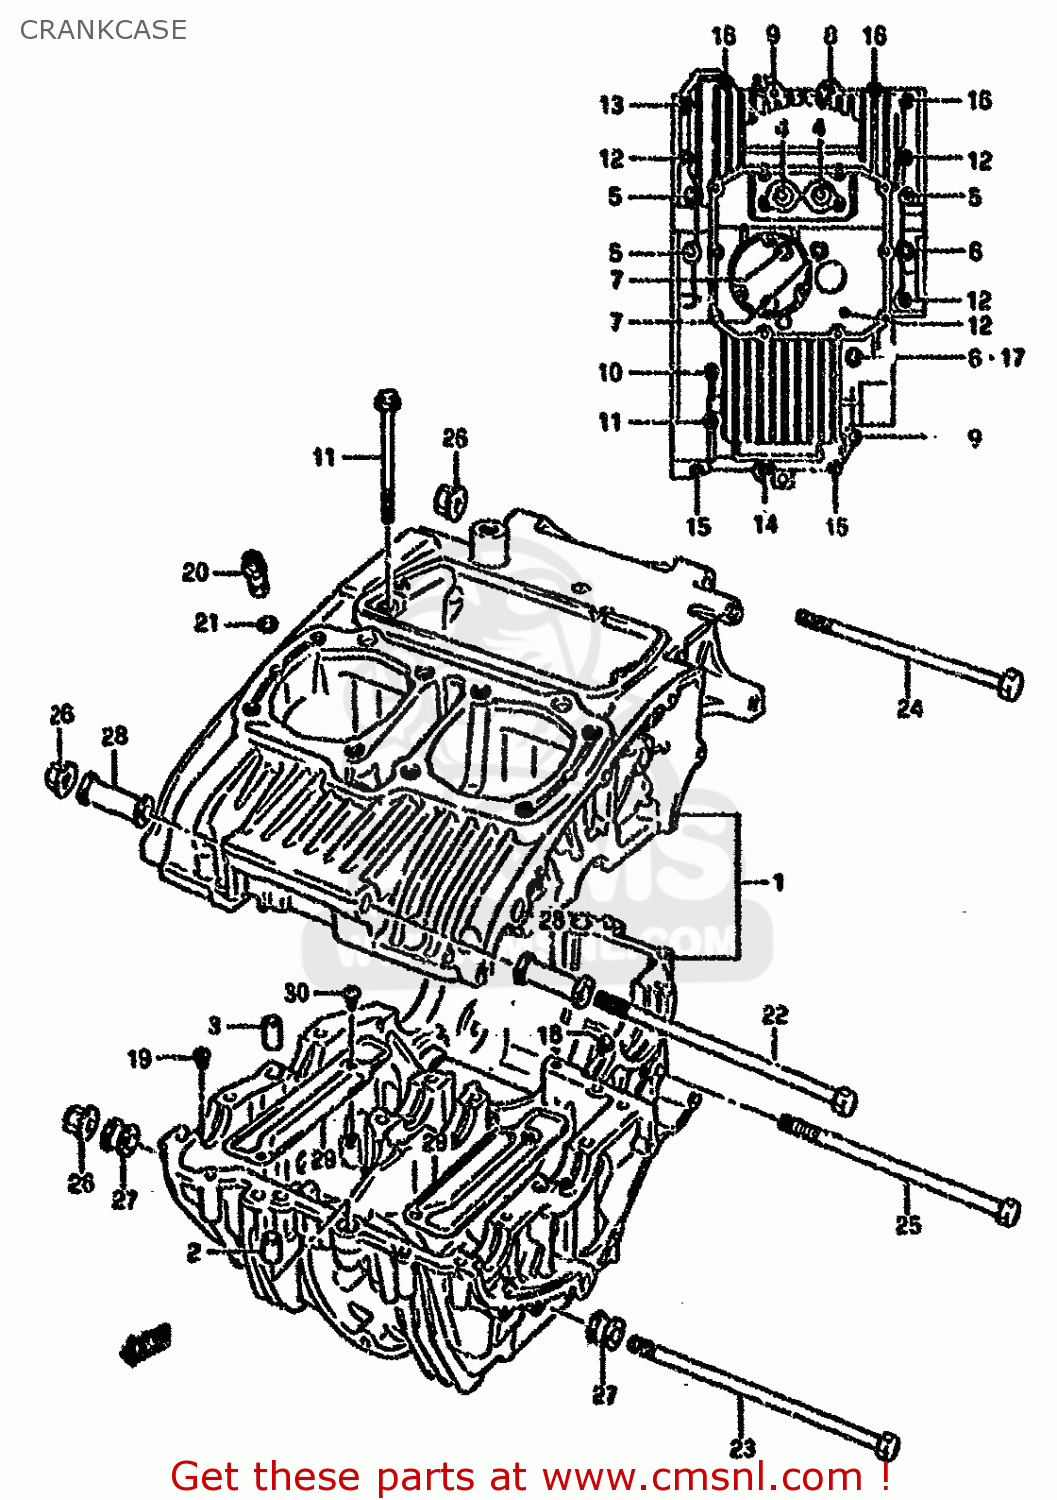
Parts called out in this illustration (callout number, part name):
1	CRANKCASE SET
2	PIN(10.4X13X22)
3	PIN (11X20)(SUS)
4	BOLT
5	BOLT(8X125)
6	BOLT(8X110)
7	BOLT(8X100)
8	BOLT
9	BOLT
10	BOLT(6X125)
11	BOLT(6X105)
12	BOLT (6X90)
13	BOLT
14	BOLT
15	BOLT
16	BOLT (6X45)
17	GASKET 8.2X14X1 (NAS)
18	JET,AIR
19	JET
20	JET
21	O RING(D:1.05,ID:3.1)
22	BOLT(10X255)
23	BOLT(10X240)
24	BOLT(10X170)
25	BOLT(10X160)
26	NUT
27	SPACER,ENG MTG(L:16.8)
28	SPACER,ENGINE MOUNT(L:65)
29	PLATE,OIL SEPARATOR
30	SCREW
